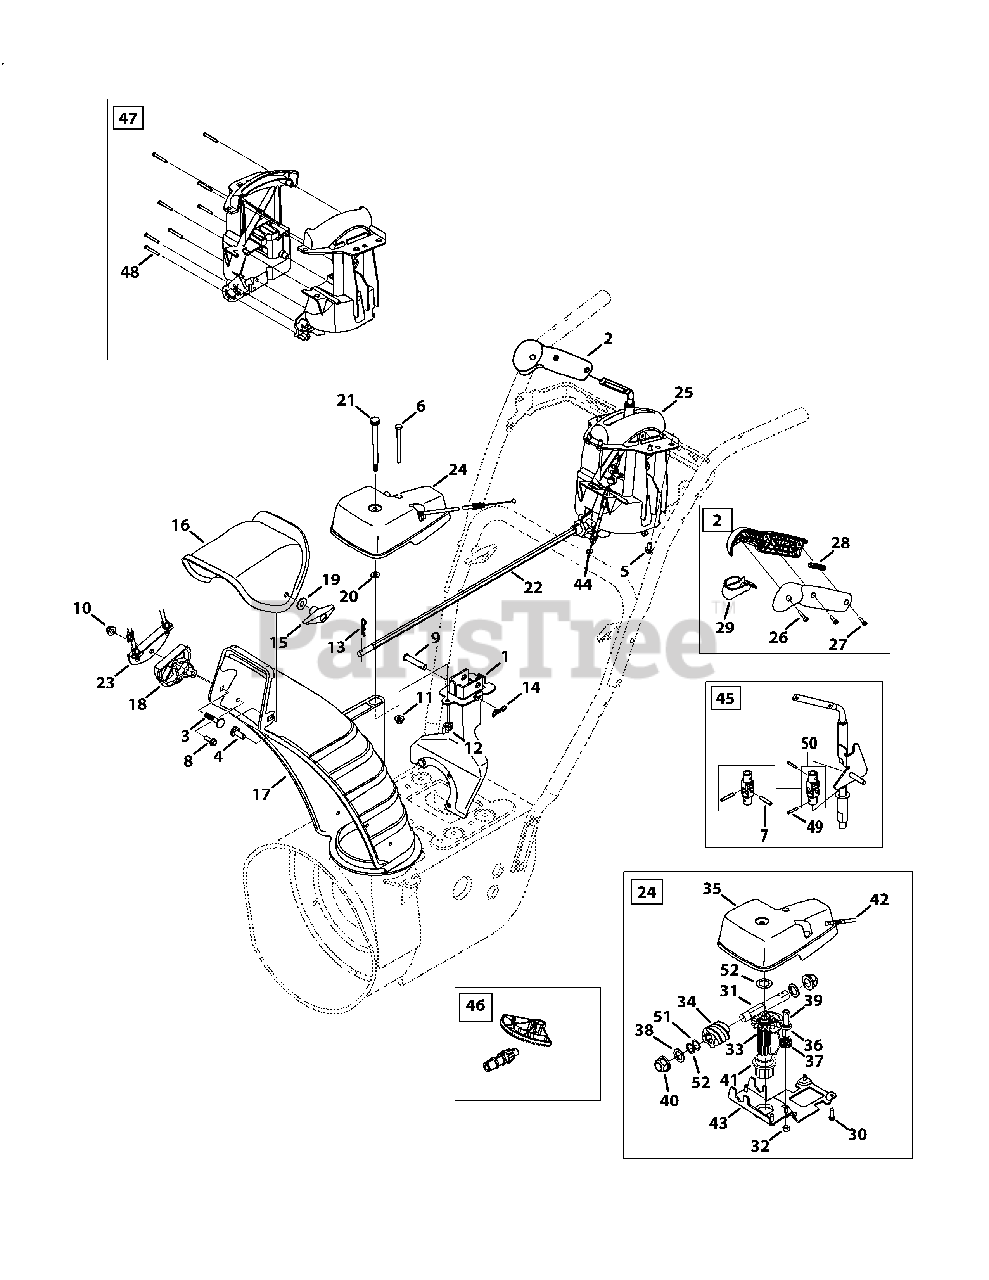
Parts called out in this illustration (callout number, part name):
1	Chute Support Bracket
2	Handle Assembly
3	Bolt, Carriage, 5/16-18 x 1.50
4	Bolt, Carrier, 5/16-18 x 1.00
5	Screw, HL, 1/4-15 x 0.50
6	Hex Head Screw, 1/4-20 x 3.00
7	Pin, Roll
8	Screw, HL, 1/4-15 x 0.750
9	Clevis Pin, 3/8 x 1.87
10	Nut, Flangelock, 5/16-18
11	Nut, Flangelock, 1/4-20
12	Wing Nut, 1/4-20
13	Internal Cotter Pin
14	Bow-Tie Cotter Pin
15	Wing Knob, 5/16-18
16	Chute, Upper
17	Chute, Lower
18	Cable Guide, Chute Tilt
19	Washer, Flat, .349 x .879
20	Washer, Flat, .25 x .630
21	Screw, Shoulder, .312 x 3.5 x 1/4-20
22	Chute Rod, 3/8 Hex
23	Cable Bracket
24	Gearbox Assembly, Chute Rotation
25	Chute Control, 4-Way
26	Screw, #8 x 1.00
27	Screw, 8-32 x .750
28	Joystick Plug
29	Joystick Trigger
30	Screw, 12-16 x .75
32	Hexlock Nut, 1/4-28
33	Gear, 14 T
34	Worm
35	Gear Cover
37	Torsion Spring, .721 ID x .474
38	Washer, Flat, .625 x 1.0 x .067
39	Screw, Shoulder, .340 x .950 x 1/4-28
40	Hex Bearing
41	Flange Bearing
44	4-Way Cable
44	Cable Clip
45	Shift Assembly
46	Gear Set Assembly
47	Handle Housing Assembly
48	Screw, #8-18 x 1.250
50	Block, Asm Joint
51	Shim Washer, .632 x 1.00 x .010
52	Shim Washer, .63 x 1.00 x .020
